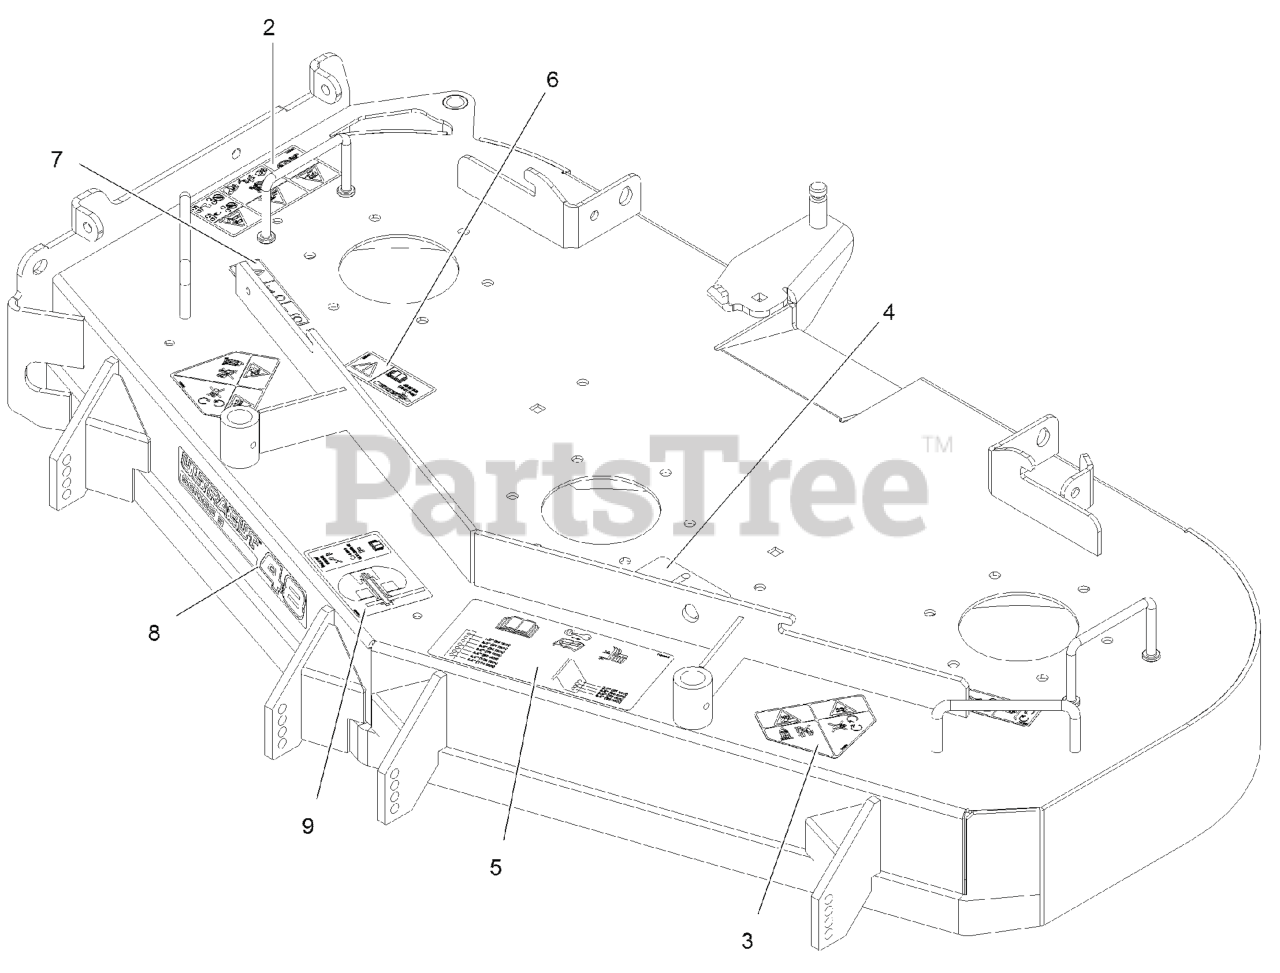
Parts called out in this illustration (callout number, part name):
2	DECAL-WARNING THROWN OBJ
3	DECAL-DANGER
4	DECAL-BELT ROUTING
5	DECAL-ANTI-SCALP
6	DECAL-TORQUE, BOLT
7	DECAL-COVER, MISSING
8	DECAL-ULTRACUT 48 SERIES 3
9	DECAL-ROLLER MOUNTING
